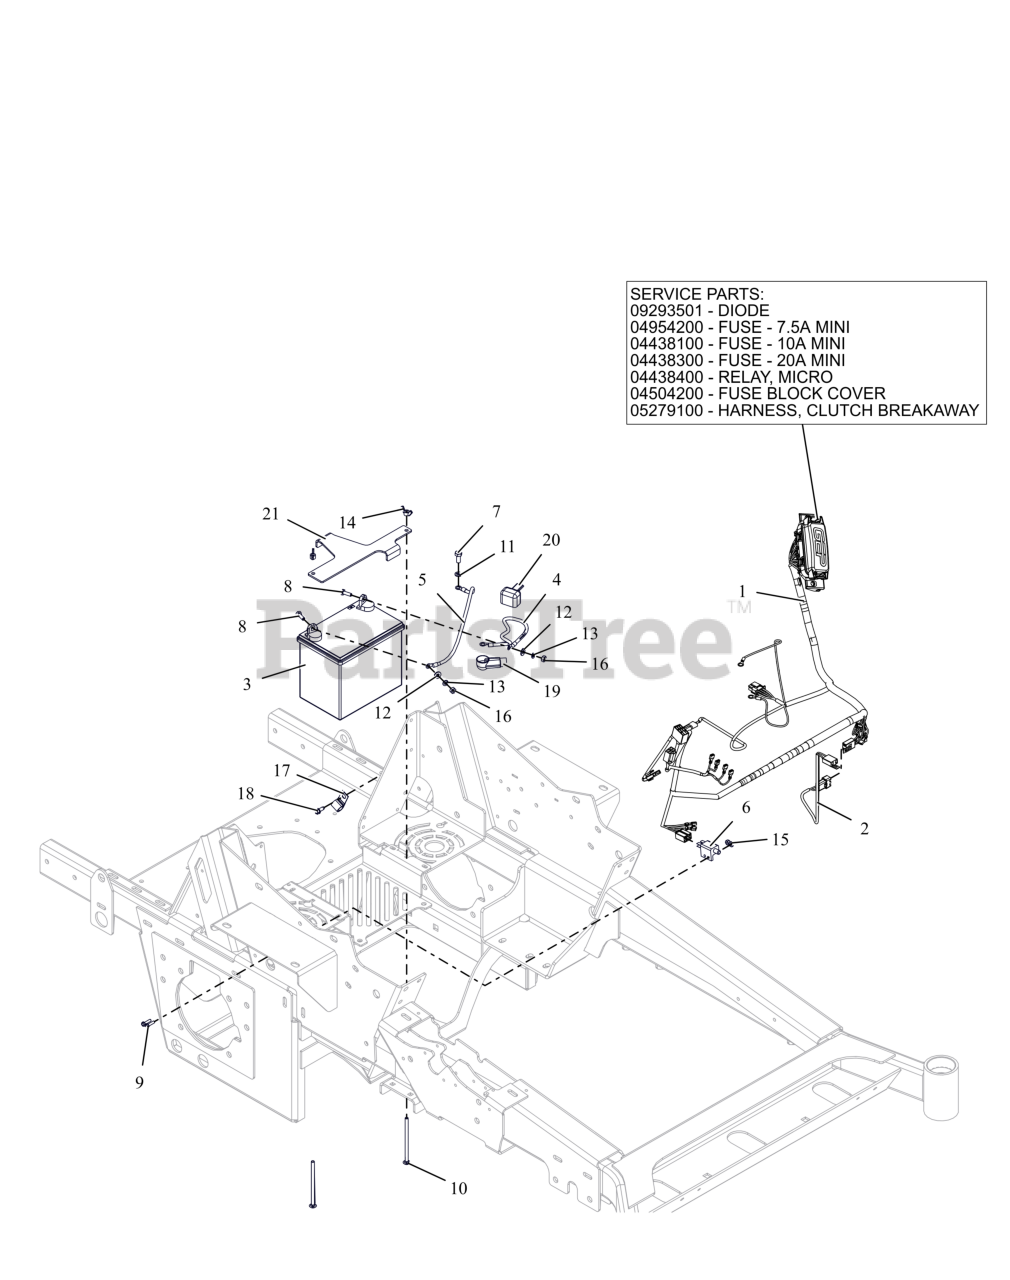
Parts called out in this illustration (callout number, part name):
1	HARNESS- WIRE PT300 MAIN
1	DIODE, CONNECTOR SHELL
1	FUSE, 7.5 AMP MINI-ATC
1	FUSE,10 AMP MINI-ATC
1	FUSE,20 AMP MINI ATC
1	RELAY,MICRO5 TERML W/RESISTOR
1	COVER, HARNESS FUSE/RELAY MOD
1	HARNESS, CLUTCH BREAKAWAY
2	HARNESS- PT300 SEAT JUMPER
3	BATTERY, 300 CCA 10U1L
4	CABLE, STARTER 13.00"
5	CABLE-GROUND .25 X 13.00 X .31
6	SWITCH- DOUBLE POLE N.O./N.O.
7	BLT, HEX M8-1.25X20 G8.8 ZCC
8	BLT, HEX .25-20X.75 G5 ZCC
9	BLT, HWH #10-24X.75 ZCC
10	BLT, RHSN .25-20X4.50 G5 ZCC
11	WSHR,LK-REG .312X.078 ZCC
12	WSHR,FLT .281X.625X.065 ZCC
13	WSHR,LK-REG .250X.062 ZCC
14	NUT, LK-WING .25-20 ZCC
15	NUT-LK-NYL #10-24 G2 ZCC
16	NUT-STD .250-20 G2 ZCC
18	SCR,TAP .25-20X.625 HWH ZCC
19	BOOT, .65ID POS
20	INSULATOR
21	HOLDDOWN- BATTERY
